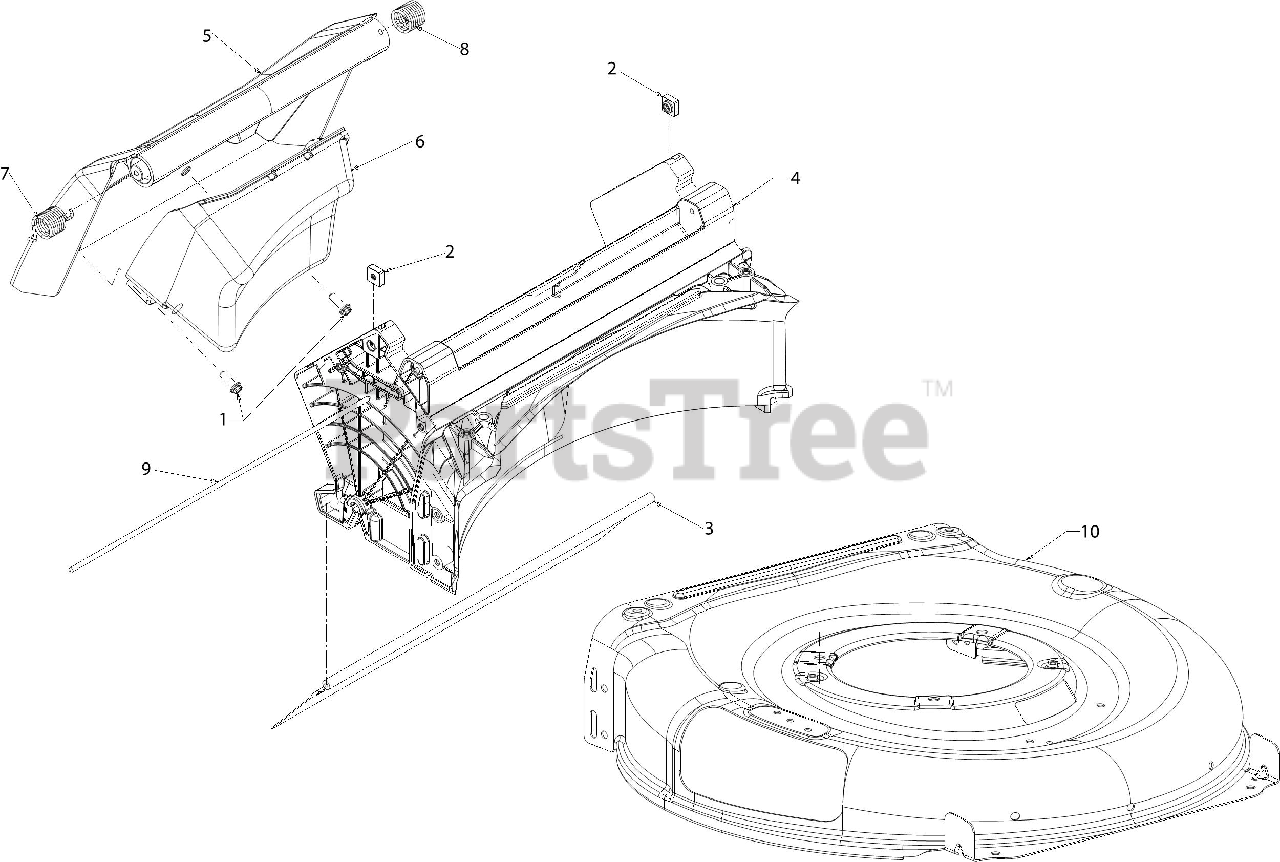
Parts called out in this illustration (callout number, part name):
1	SCREW 1/4 x .750
2	SQUARE LOCK NUT 1/4X20
3	TRAILSHIELD
4	REAR BAFFLE
5	REAR DOOR
6	MULCH PLUG
7	TORSION SPRING (RH)
8	TORSION SPRING (LH)
9	PIVOT ROD
